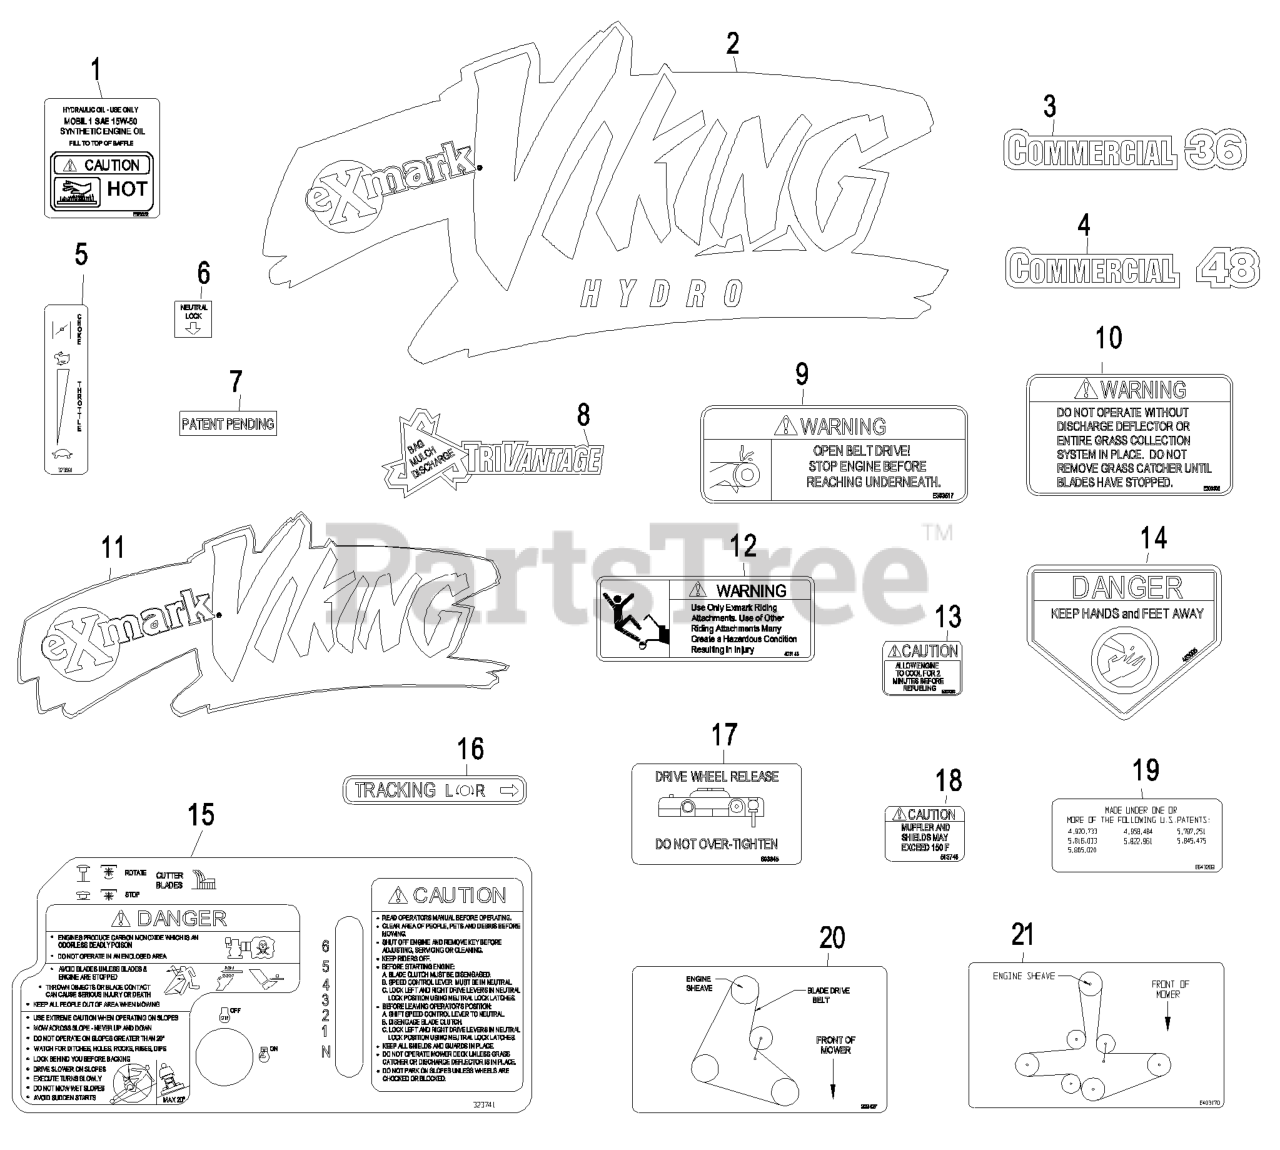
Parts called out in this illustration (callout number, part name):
3	DECAL,COMMERCIAL 36
4	DECAL,COMMERCIAL 48
5	DECAL,THROTTLE
6	DECAL,NEUTRAL LOCK
7	Decal, Patent Pending
9	DECAL,BELT DRIVE
10	DECAL-WARNING, DISCHARGE
12	DECAL,SULKY WARNING
14	DECAL-DANGER
16	DECAL,TRACKING ADJUST
17	DECAL,DRIVE RELEASE
20	DECAL,BELT ROUTING 32/36
